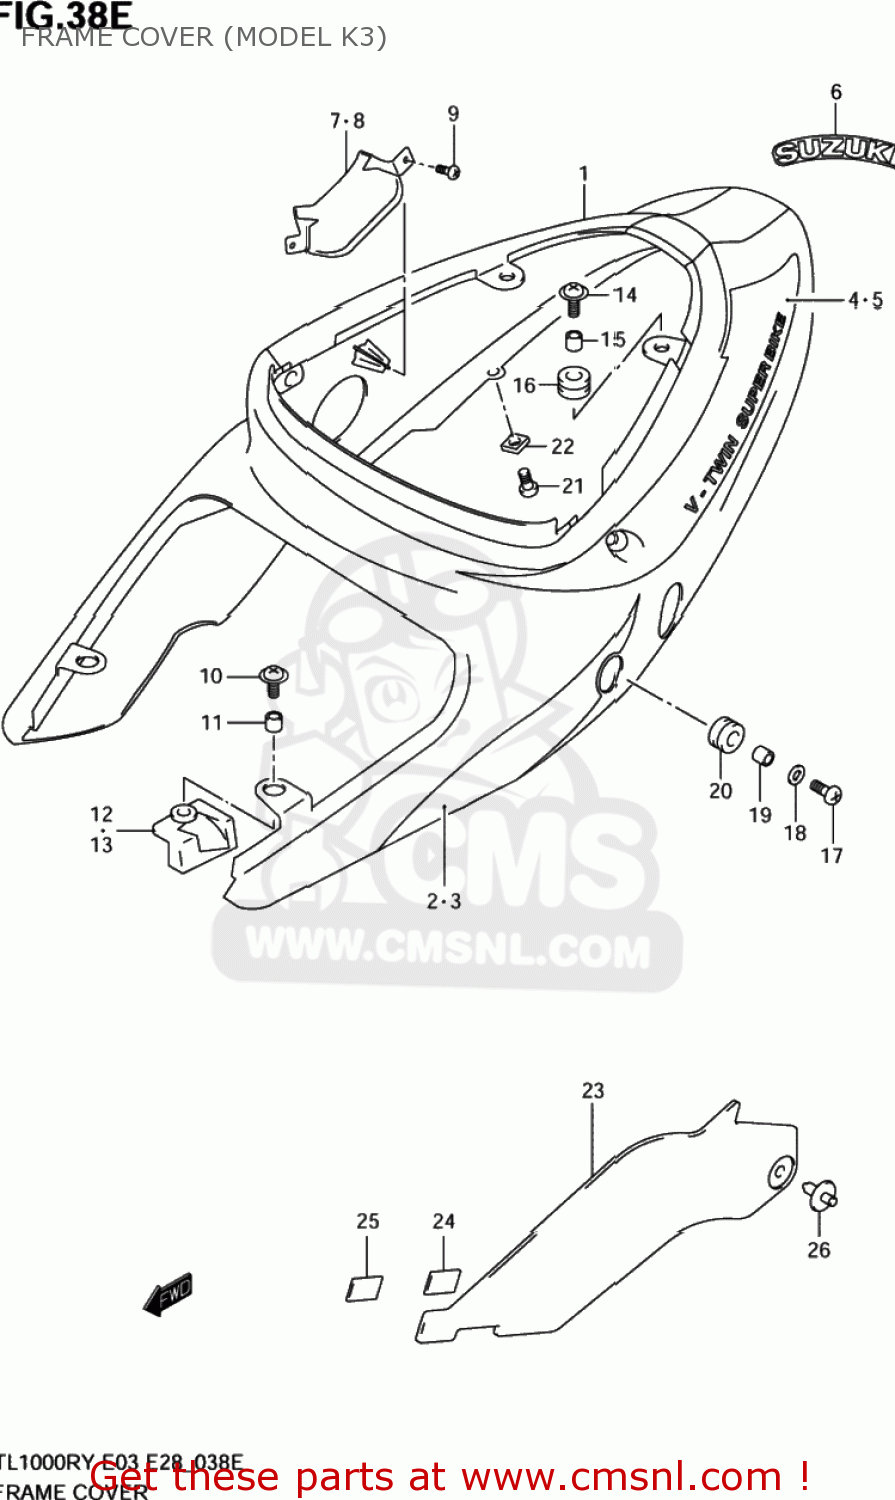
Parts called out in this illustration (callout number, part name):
1	COVER,FRAME(WHITE)
2	TAPE,FRAME COVER STRIPE,R
3	TAPE, LH LOWER (BLUE)
4	TAPE,FRAME COVER,R
5	TAPE, LH UPPER
6	EMBLEM,SUZUKI
7	CAP,FRAME COVER HOLE,R
8	CAP,FRAME COVER HOLE,L
9	SCREW
10	SCREW(6X20)
11	SPACER(6.5X9X9)
12	CUSHION,FRAME COVER,R
13	CUSHION,FRAME COVER,L
14	SCREW(6X20)
15	SPACER(6.5X10X9.4)
16	CUSHION
17	SCREW(6X20)
18	WASHER(6.5X22X1.6)
19	SPACER(6.5X9X6.7)
20	CUSHION
21	CLIP
22	NUT
23	COVER,FRAME,FRONT,RIGHT
24	FASTENER,NO.1
25	FASTENER,NO.2
26	CLIP(GRAY)
